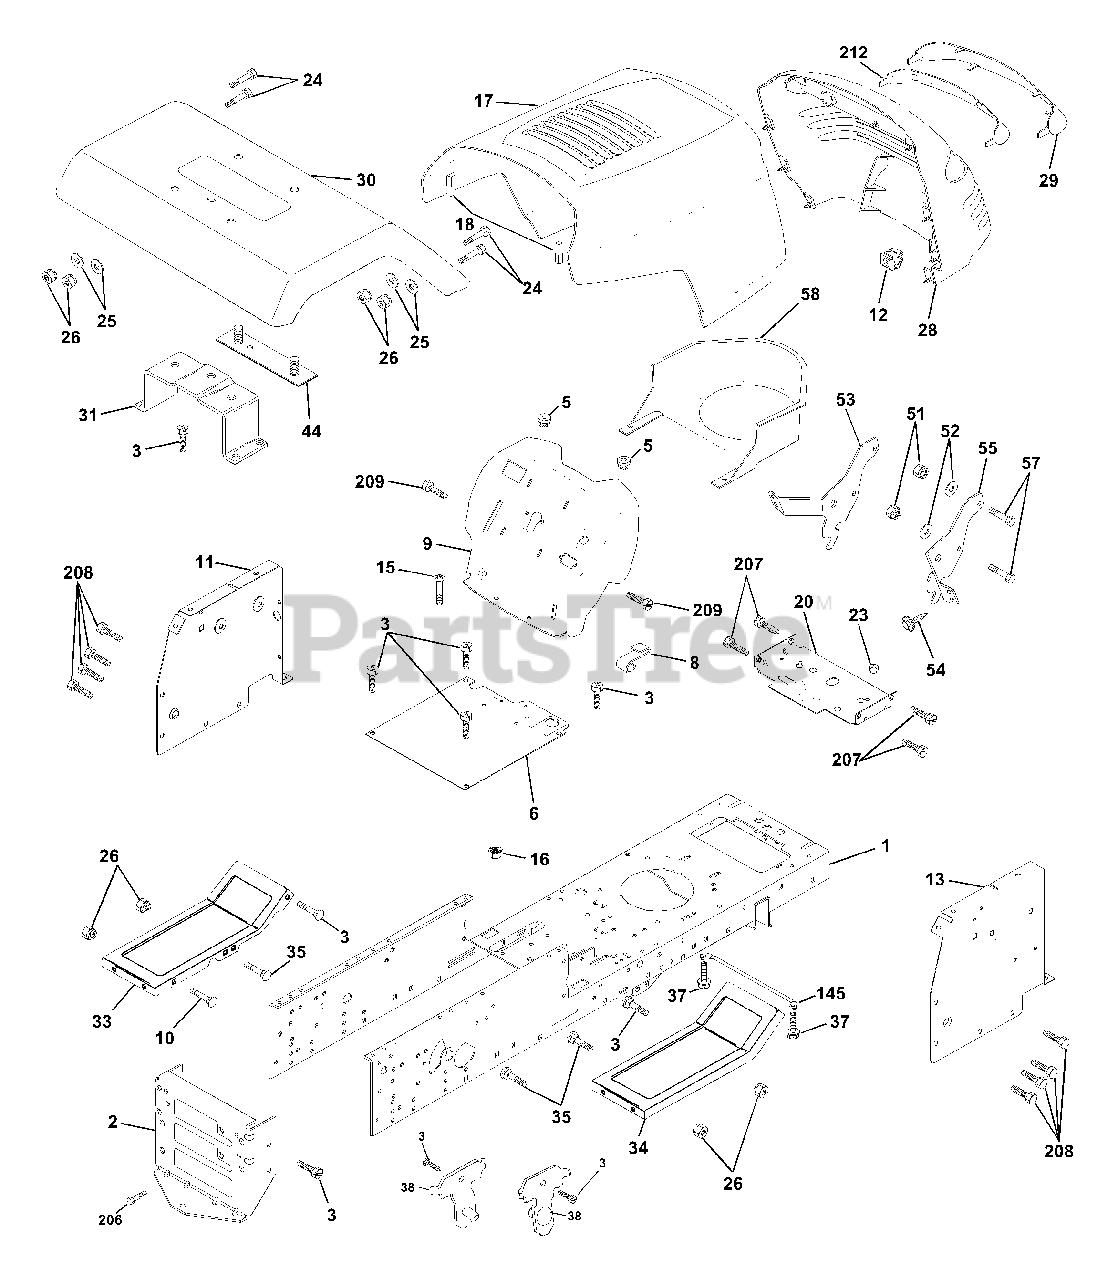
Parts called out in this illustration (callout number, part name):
2	Drawbar
3	Screw 3/8-16 x 3/4
5	Bumper Hood/Dash
6	Saddle
8	Clip
9	Dash
10	Bolt Rd Hd Sqnk. 3/8-16 x 1
11	Panel Dash Lh
12	Clip Tinnerman Grille P/L
13	Panel Dash Rh Slkscr
15	Screw Mach Trhd 5/16-18 UNC x 3/4
16	Nut Keps 5/16-18 UNC
17	Hood Pnt Steel Private Label
18	Bumper Hood
20	Plate Mtg Battery/Fuel Tank
23	Bushing Snap Nyl. Blk Fuel Line
24	Bolt Fin Hex 3/8-16 Unc x 1 Gr. 5
25	Washer 13/32 x 13/16 x 12 Ga.
26	Nut Lock Hex w/Ins 3/8-16 Unc
28	Grill
29	Lens
31	Bracket Fender Support
33	Footrest Pnt. Lh
34	Footrest Pnt. Rh
35	Bolt Rd Hd Sht. Sqnk. 3/8-16 x 3/4
37	Screw Thdrol 5/16-18 x 1/2
38	Bracket Asm. Pvt. Mwr. Rear
44	Strap Asm Pnt Fender
51	Nut Lock Hex W/Ins. 1/4-20
52	Washer 9/32 x 7/8 x 16 Ga.
53	Bracket Grille LH
54	Screw Hex Wshd 8-18 x 7/8
55	Bracket, Grille RH
57	Bolt Fin Hex 1/4-20 x 3/4
58	Air Duct Engine
145	Rod Pivot Chassis/Hood
206	Bolt Shoulder 5/16-18
207	Screw Thdrol 5/16-18 x 1/2
208	Screw Thdrol 3/8-16 x 1/2
209	Screw Hex Wsh Thdrol 3/8-16 x 3/4
